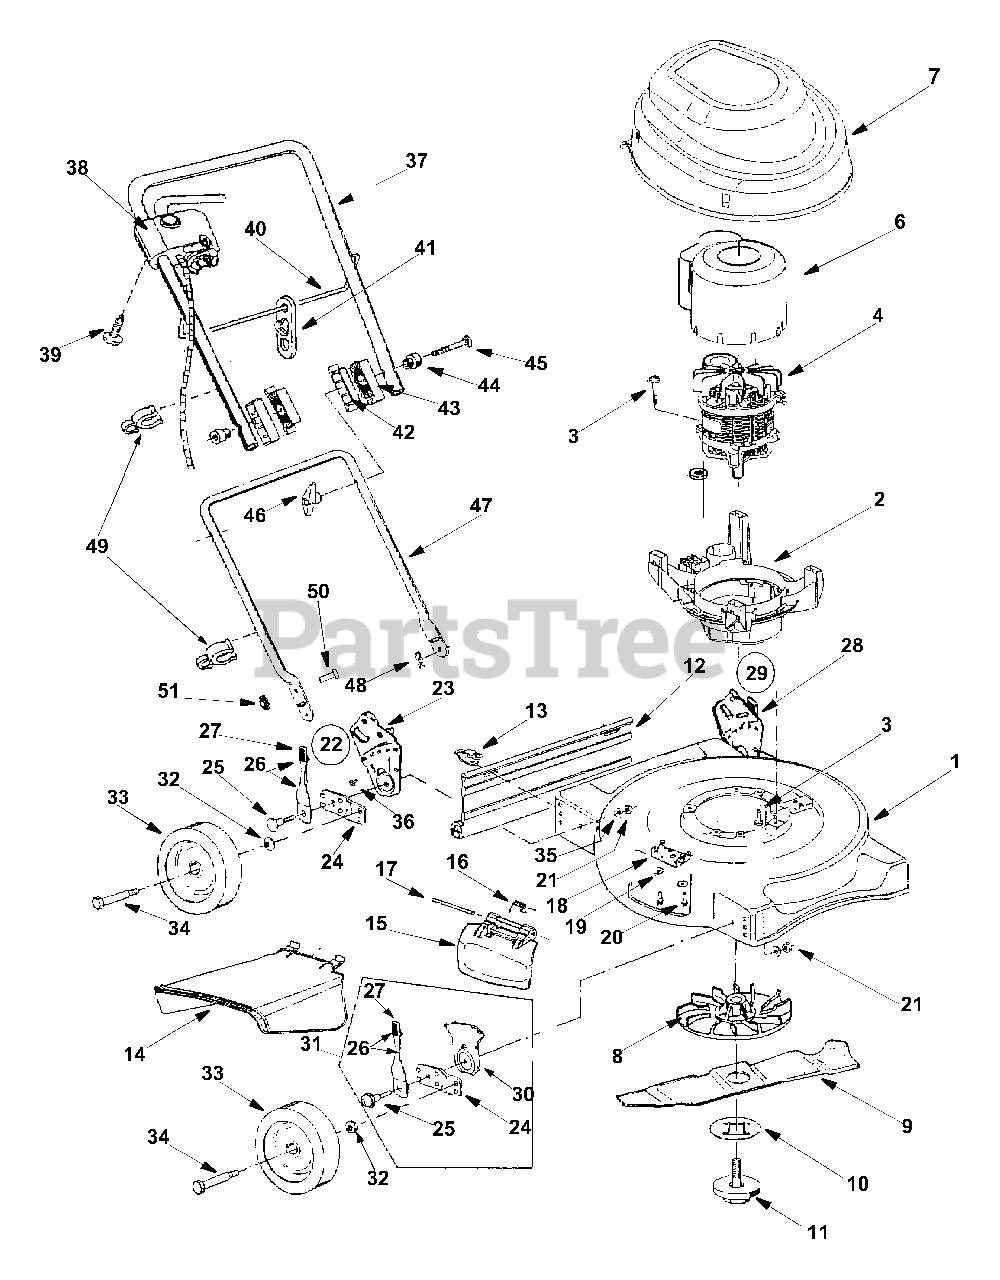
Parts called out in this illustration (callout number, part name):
1	18" Deck Green
2	Motor Base
3	Screw, M7 x 25
4	Electric Motor, 115V, 1500W
6	Air Guide Cover
8	Blade Hub Assembly
9	Mulching Blade
10	Blade Locking Plate
11	Blade Screw
12	Trailing Shield
13	Hinge Clip
14	Side Discharge Deflector
15	Mulch Plug
16	Torsion Spring
17	Hinge Pin
19	Beleville Washer
20	Screw
21	Flange Lock Nut
22	Handle Bracket Assy. RH
23	Handle Bracket RH
25	Shoulder Bolt
26	Lever and Knob Ass'y.
27	Height Adjustment Knob
28	Handle Bracket LH
29	Handle Bracket Assembly LH
30	Adjusting Plate
31	Height Adjustment Assembly RH
32	Bell Washer
33	Wheel
34	Axle Bolt
35	Bell Washer
36	Screw
37	Upper Handle
38	Switch Plug Combination
39	Screw
40	Guide Rod
42	Lower Handle Insulator
43	Upper Handle Insulator
44	Insulating Knob Spacer
45	Carriage Bolt
46	Wing Nut
49	Cable Guide
50	Screw
51	Handle Knob
